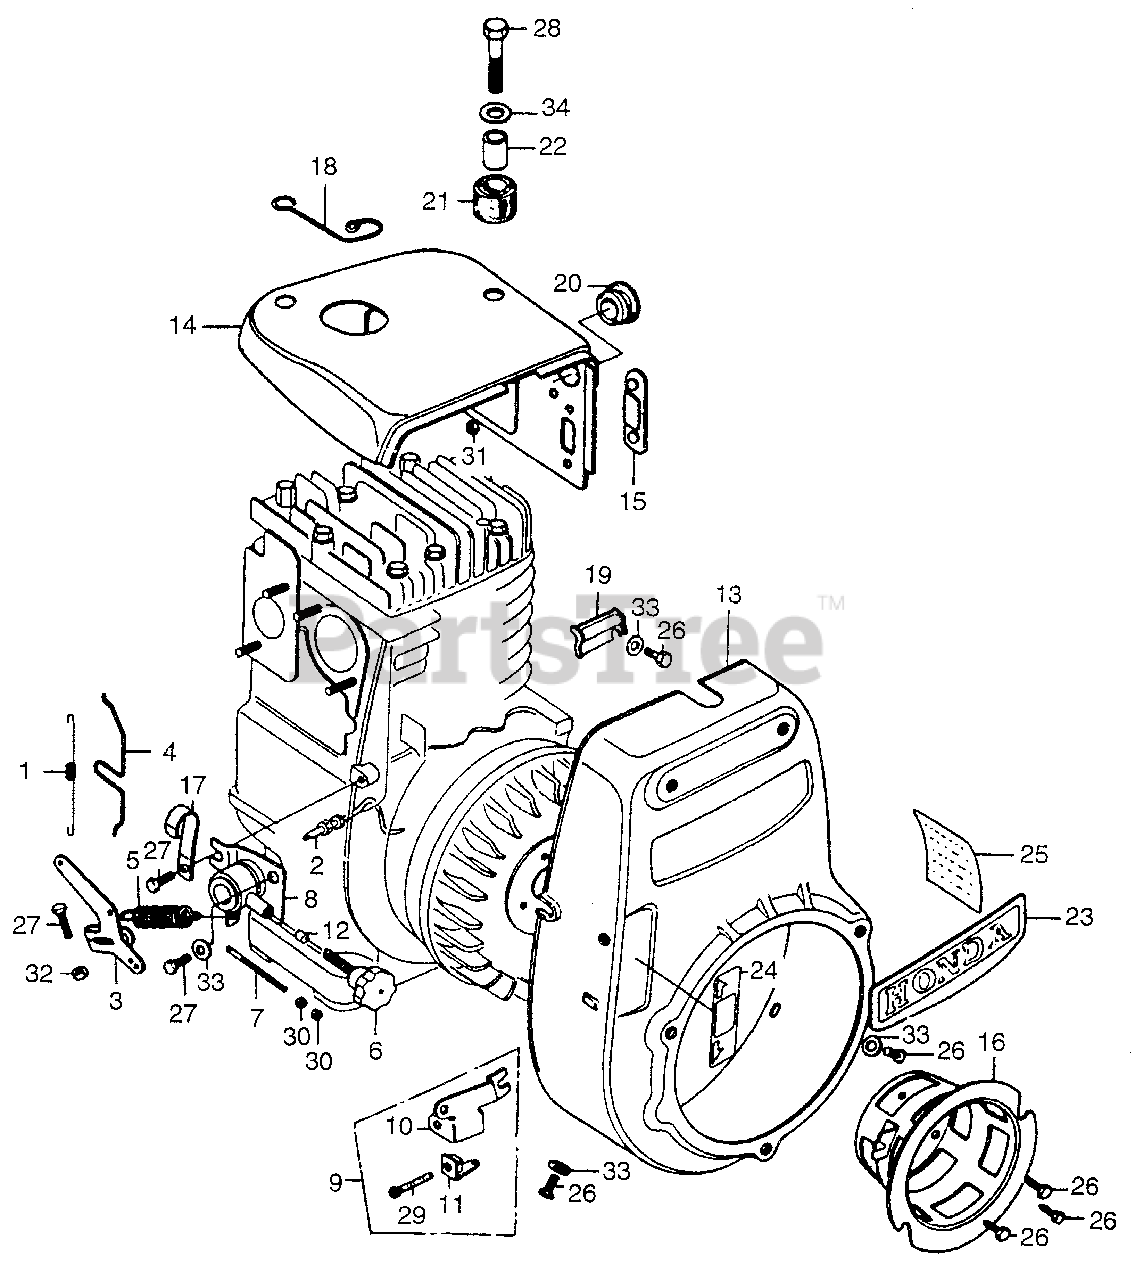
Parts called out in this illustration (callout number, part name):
1	SPRING, THROTTLE RETURN (NOT AVAILABLE)
2	SHAFT, GOVERNOR ARM (NOT AVAILABLE)
3	ARM, GOVERNOR
4	ROD, GOVERNOR (NOT AVAILABLE)
5	SPRING, GOVERNOR (NOT AVAILABLE)
6	SCREW, GOVERNOR ADJUST (NOT AVAILABLE)
7	BOLT, SPRING ADJUSTING (NOT AVAILABLE)
8	LEVER, CONTROL (NOT AVAILABLE)
12	BUSHING, CONTROL
13	COVER, FAN *R8* (BRIGHT RED) (NOT AVAILABLE)
14	COVER SIDE *R8* (BRIGHT RED)
15	DEFENDER, SIDE COVER
16	PULLEY, STARTER (NOT AVAILABLE)
17	CLAMP, WIRE
18	CLAMP, IGNITION WIRE (NOT AVAILABLE)
21	RUBBER, STOPPER (NOT AVAILABLE)
22	COLLAR, DISTANCE
23	EMBLEM (NOT AVAILABLE)
24	PLATE, THROTTLE (NOT AVAILABLE)
25	MARK, OIL CAUTION (NOT AVAILABLE)
26	BOLT, HEX. (6X12)
27	BOLT, HEX. (6X16)
28	BOLT, HEX. (8X32)
30	NUT, HEX. (4MM)
31	NUT, HEX. (5MM)
32	NUT, HEX. (6MM)
33	WASHER, PLAIN (6MM)
34	WASHER, PLAIN (8MM)
